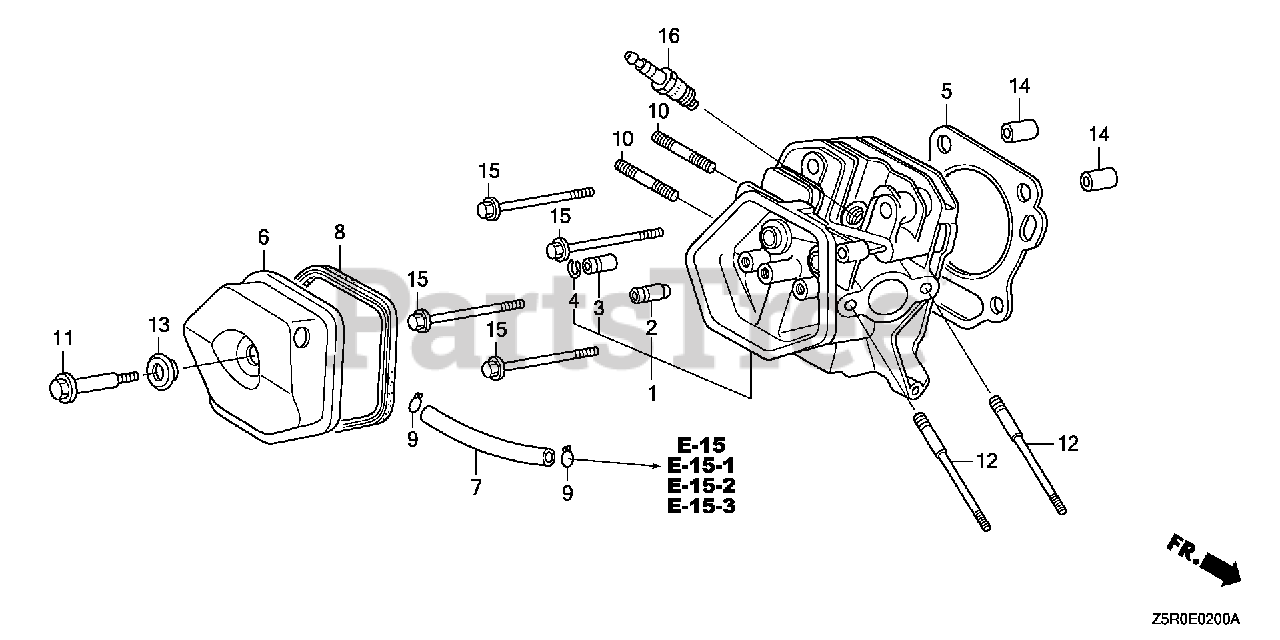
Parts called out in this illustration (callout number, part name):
1	CYLINDER HEAD
2	GUIDE, VALVE (OS)
3	GUIDE, EX. VALVE (OS)
4	CLIP, VALVE GUIDE
5	GASKET, CYLINDER HEAD (NIPPON LEAKLESS)
6	COVER, HEAD
6	COVER, CYLINDER HEAD
8	GASKET, CYLINDER HEAD COVER
10	BOLT 2, STUD (8X32)
11	BOLT, HEAD COVER
12	BOLT, STUD (8X106)
12	BOLT, STUD (8X115)
13	WASHER, HEAD COVER
14	PIN A, DOWEL (12X20)
15	BOLT, FLANGE (10X80)
16	SPARK PLUG (BPR5ES) (NGK)
16	SPARK PLUG (W16EPR-U) (DENSO)
